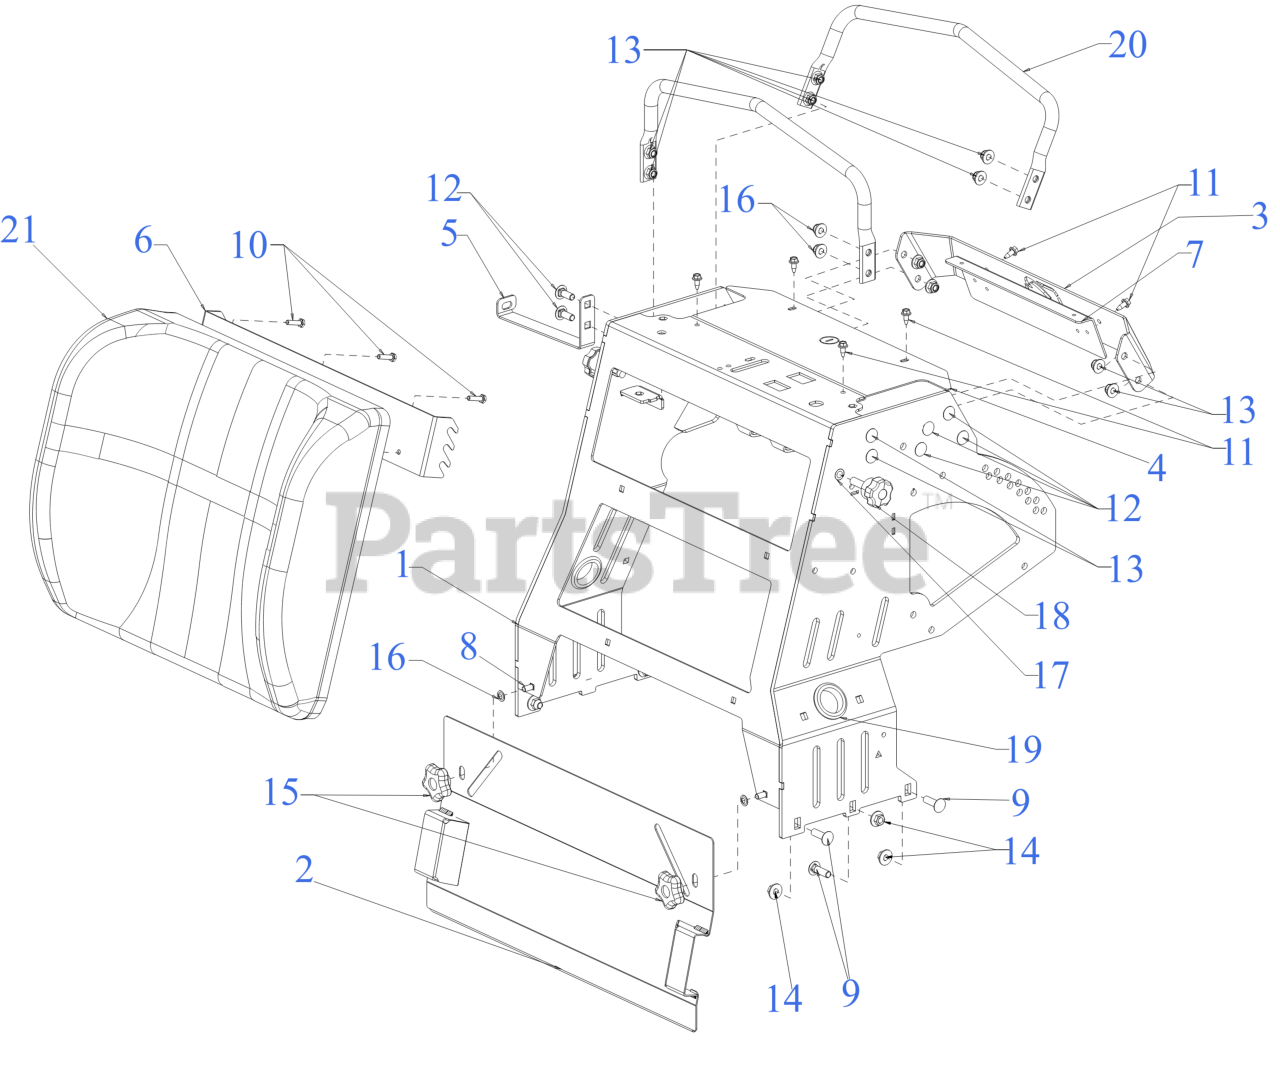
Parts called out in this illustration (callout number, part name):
1	CONTROL BASE
2	PANEL COVER
3	BASE CONTROL
4	DASH PANEL
5	TANK SUPPORT BRACKET
6	PAD MOUNT
7	DASH SUPPORT
8	CARRIAGE BOLT 5/16-18 x .75
9	CARRIAGE BOLT 3/8-16 X1.25 GR5
10	SCREW 1/4-20 X1.00 GR5
11	SCREW 1/4-20X.625
12	CARRIAGE BOLT 3/8-16 x 1.00 GR5
14	FLANGE LOCK NUT
15	STAR KNOB 5/16-18
17	RIV NUT 3/8-16
18	SEAT ADJUST KNOB 3/8-16 x 1.50
19	RUBBER GROMMET (1.50X2.13X.563)
20	TUBE
